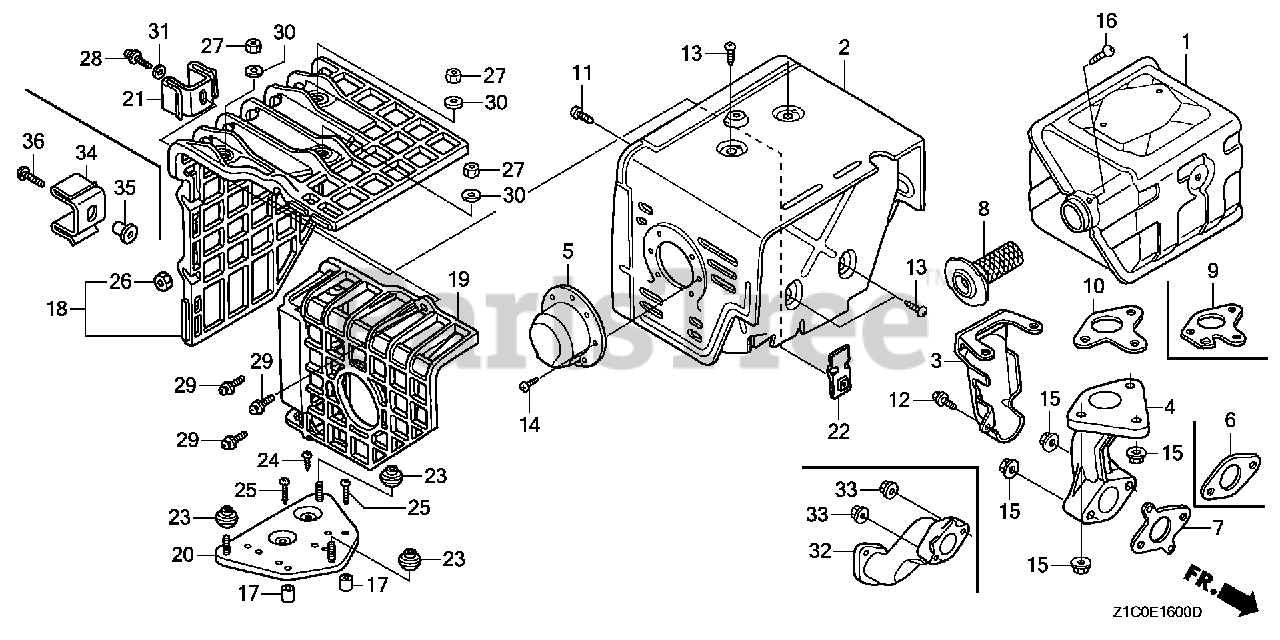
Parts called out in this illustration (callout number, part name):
1	MUFFLER (100DB)
2	PROTECTOR, MUFFLER
3	PROTECTOR, EX. PIPE
7	GASKET, EX. PIPE
10	GASKET, MUFFLER
11	SCREW, TAPPING (6X10)
12	BOLT, FLANGE (6X12) (CT200)
13	SCREW, TAPPING (5X8)
15	NUT, FLANGE (8MM)
